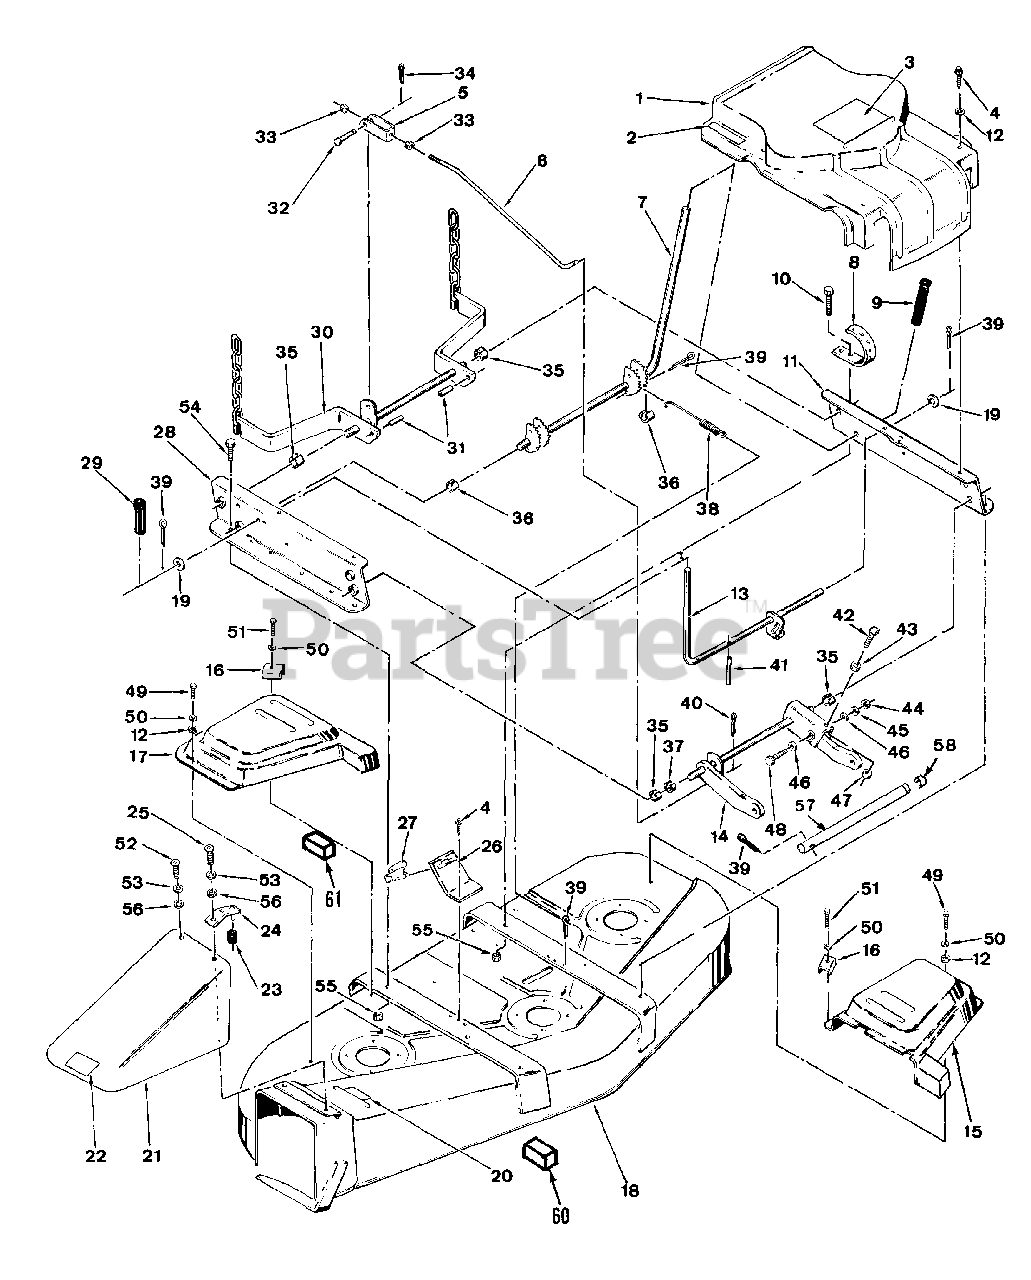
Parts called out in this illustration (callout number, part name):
1	Center Cover
3	Decal - Safety
4	1/4 C x 3/8 Self Tapping Screw
5	Clevis
6	Timing Rod
7	Cam Structure
8	Indicator Plate
9	Handle Grip
10	3/8 F x 1 Hex Hd. Capscrew
11	L. H. Rail
12	1/4 Flat Washer
13	Handle Structure
14	Front Lift Arm Structure
15	Spindle Cover - L. H.
16	Clip
17	Spindle Cover - R. H.
18	Deck Structure
19	1/2 SAE Washer
20	Cut Line Decal
21	Deflector
23	Rubber Spacer
24	Spring Arm Assembly
25	5/16-18 x 3/4 Socket Hd Screw
26	Switch Plate
27	Switch Assembly
28	R. H. Rail
29	Handle Grip
30	Rear Lift Arm Structure
31	Roll Pin
32	PIN, 3/8 x 1 1/16" Clevis
33	3/8 24 Hex Nut
34	Cotter Pin - 3/32 x 3/4
35	Blue Ring
36	White Ring
37	Red Ring
39	Cotter Pin - 5/32 x 1
40	Cotter Pin
41	Roll Pin, 3/16 x 1 5/8
42	5/16-18 x 1-1/4 Sq Hd Setscrew
43	5/16 Jam Nut
44	3/8 Hex Nut
45	3/8 Lock Washer
46	3/8 Flat Washer
47	5/16 Hex Nut
48	3/8-24 x l-1 /4 Hex Hd Capscrew
49	1/4 C x 1/2 Hex Hd Capscrew
50	1/4 Lock Washer
51	1/4 C x 1 Hex Hd Capscrew
52	5/16-18 x 1/2 Socket Hd Screw
53	5/16 Lock Washer
54	3/8 F x 3/4 Hex Hd Capscrew
55	3/4-24 Lock Nut
56	5/16 Flat Washer
57	Support Rod
58	RING, 5/8" External Retaining
60	1-3/4" Leveling Block
61	1-1/2" Leveling Block
